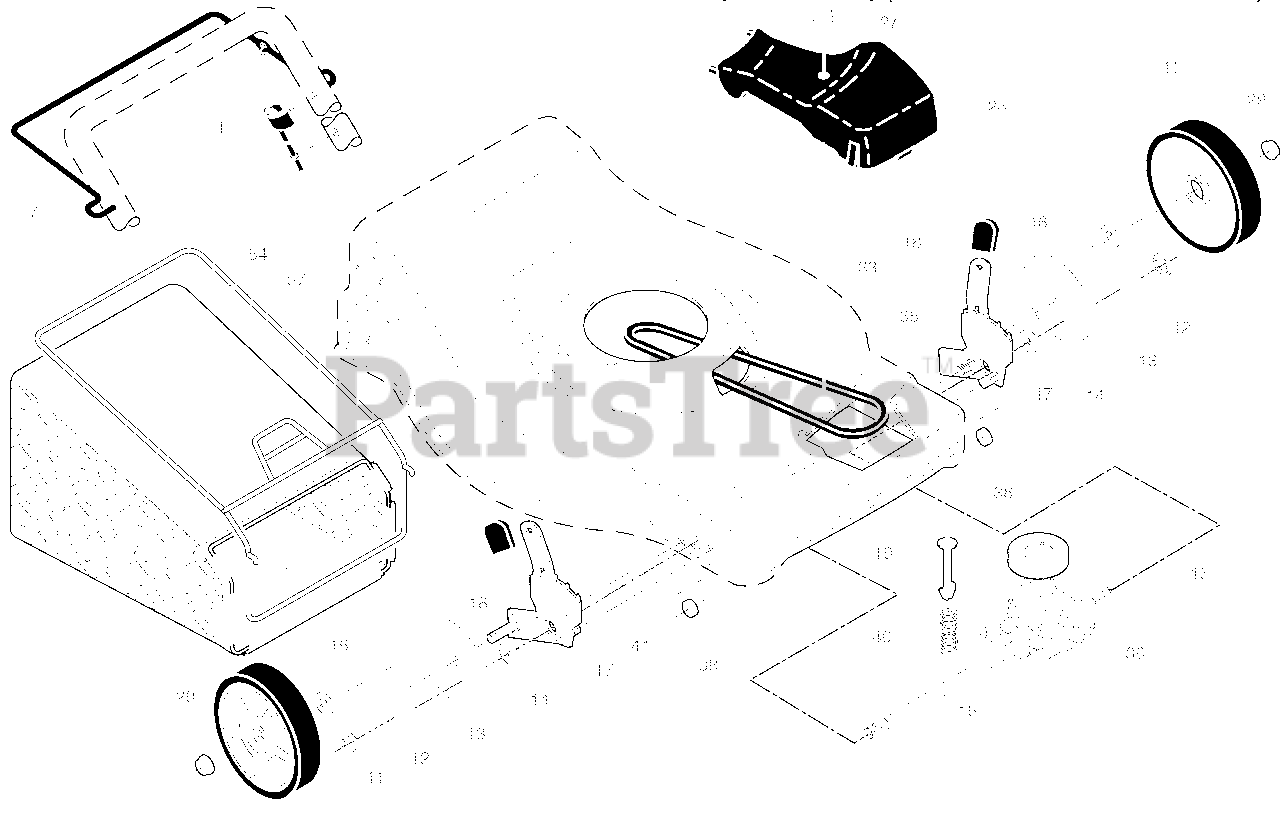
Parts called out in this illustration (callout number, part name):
1	CABLE, DRIVE CONTROL
7	Control Bar, Drive
11	WHEEL AND TIRE ASSEMBLY-FRONT
14	Dust Cover
15	Pawl, Drive
16	Washer, Flat 3/8
17	BEARING
18	Selector Knob
19	Retainer, Spring
27	Pan Head Tapping Screw #10-24
28	DRIVE COVER
29	Nut, Hex
33	DRIVE BELT
35	KIT,WHEEL ADJUSTER, RH (INCLUD
36	Gear Case Assembly, Complete
38	Lock Nut 1/4-20
41	KIT,WHEEL ADJUSTER, RH (INCLUD
57	BAG FRAME
